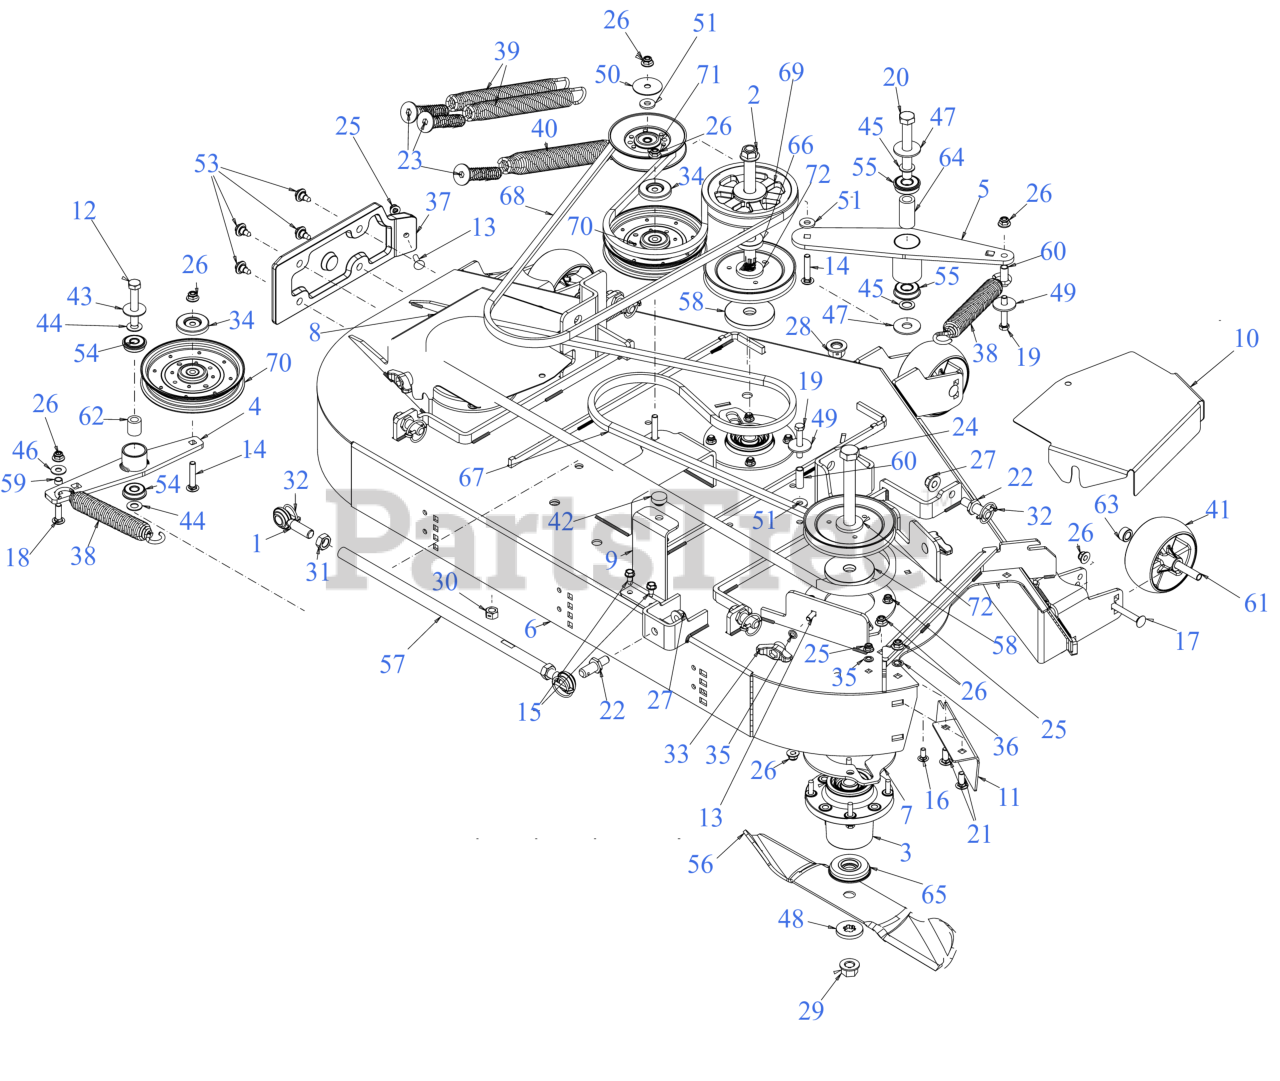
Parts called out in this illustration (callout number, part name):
1	MALE ROD END
2	SPINDLE SHAFT
3	SPINDLE ASSEMBLY
4	IDLER BRACKET
5	IDLER BRACKET
6	54" FAB DECK
7	SPINDLE SUPPORT PLATE TOP & BOTTOM
8	BELT COVER (LH)
9	DECK STOP BRACKET
10	BELT COVER (RH)
11	BAFFLE
12	SCREW-HEX 1/2-13 x 3.00
13	CARRIAGE BOLT 5/16-18 x 1.00
14	CARRIAGE BOLT 3/8-16 x 2
15	SCREW 5/16-18 x .750
16	CARRIAGE BOLT 5/16-18 x .75
17	CARRIAGE BOLT 3/8-16 x 4.00 GR5
18	CARRIAGE BOLT 3/8-16 X1.25 GR5
19	SCREW 3/8-16 x 2.25 GR5
20	SCREW 5/8-18X4.5 GR5
21	CARRIAGE BOLT 3/8-16 x 1.00 GR5
23	SPRING INSERT SCREW
24	SPINDLE SHAFT
25	FLANGE LOCK NUT 5/16-18
29	FLANGE NUT - 5/8-18 GDE 8
30	HEX NUT CTR LK 1/2-13
31	HEX JAM NUT 5/8-18
32	LYNCH PIN .1875
33	WING KNOB 5/16-18
34	PULLEY CAP
35	PUSH NUT
36	PUSH NUT
37	DECK SKID PLATE (LH)
38	SPRING 1.25" DIA x 8.5" LONG
39	EXTENTION SPRING 1.20 x 11.35
40	EXTENSION SPRING 1.44 OD x 11.36
41	DECK WHEEL
41	WHEELS-DELUXE 5"
42	RUBBER BUMPER 1.000 x .313
43	WASHER .51 x 1.5 x .07
44	FLAT WASHER .510 x .995
45	FLAT WASHER
46	WASHER-.395 x 1.0 x .62
47	FLAT WASHER 0.635xX1.755x0.110
48	FLAT WASHER - SPECIAL
49	FLAT WASHER .406X1.500X.105
50	HUB CAP WASHER .406 x 1.92 x .060
51	FLAT WASHER .406ID X1.0 OD
52	Not Applicable
53	SHOULDER SCREW .43X.29X5/16-18 TT
54	ROLLER BEARING .5X1.37X.44
55	BALL BEARING W/RET
56	19" BLADE
57	TUBE .565 X .750 X 18.75"LG
58	DECK SPINDLE SPACER
59	SPACER
60	SPACER
61	SPACER .38X.49X3.05LG
62	SPACER 0.51 x 0.88 x 1.00
63	SPACER-.505 1D
64	SPACER 0.63 x 1.00 x 2.01
65	SPACER 0.790 x 2.75 x 0.486
66	SPACER
67	BELT-B SECTION 119.45"
68	BELT SEC B x 90.30
69	PULLEY-6.96 OD x .750 ID
70	IDLER PULLEY
71	IDLER PULLEY 5.06 OD
72	V-PULLEY 6.426"
